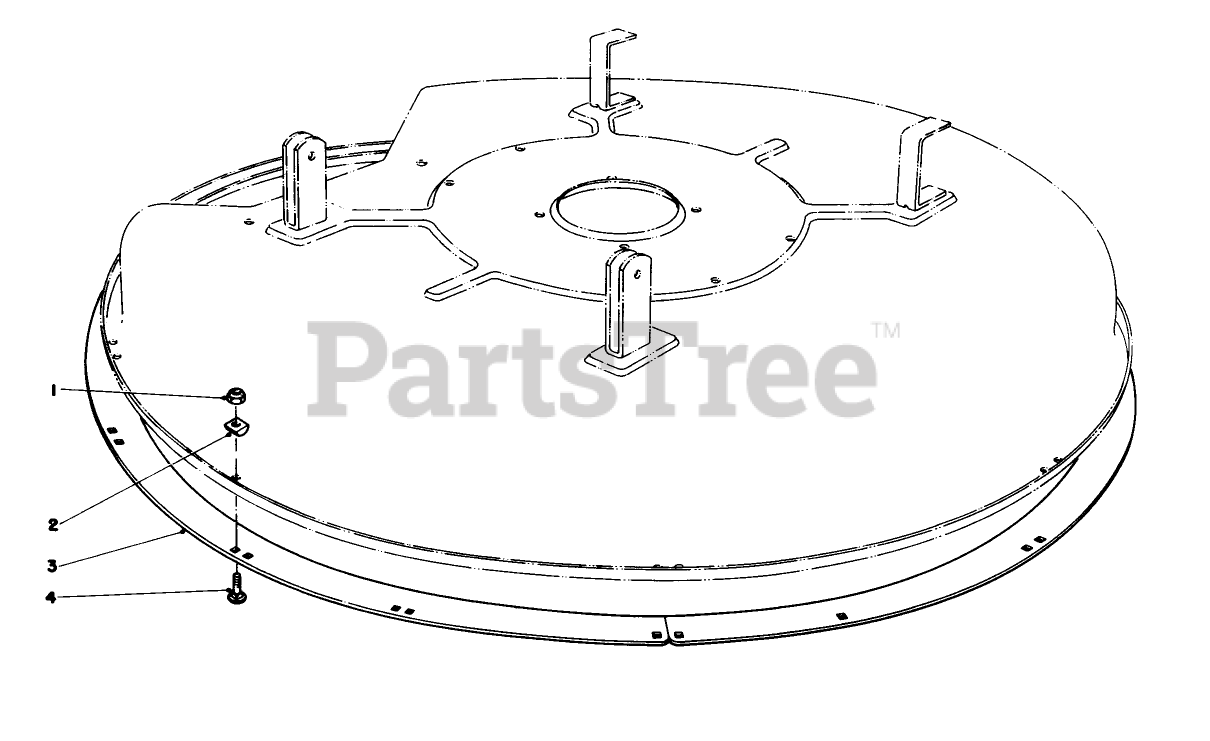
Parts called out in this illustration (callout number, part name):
1	NUT-LOCK, NI
3	DECK RING *B
4	BOLT-CARR
